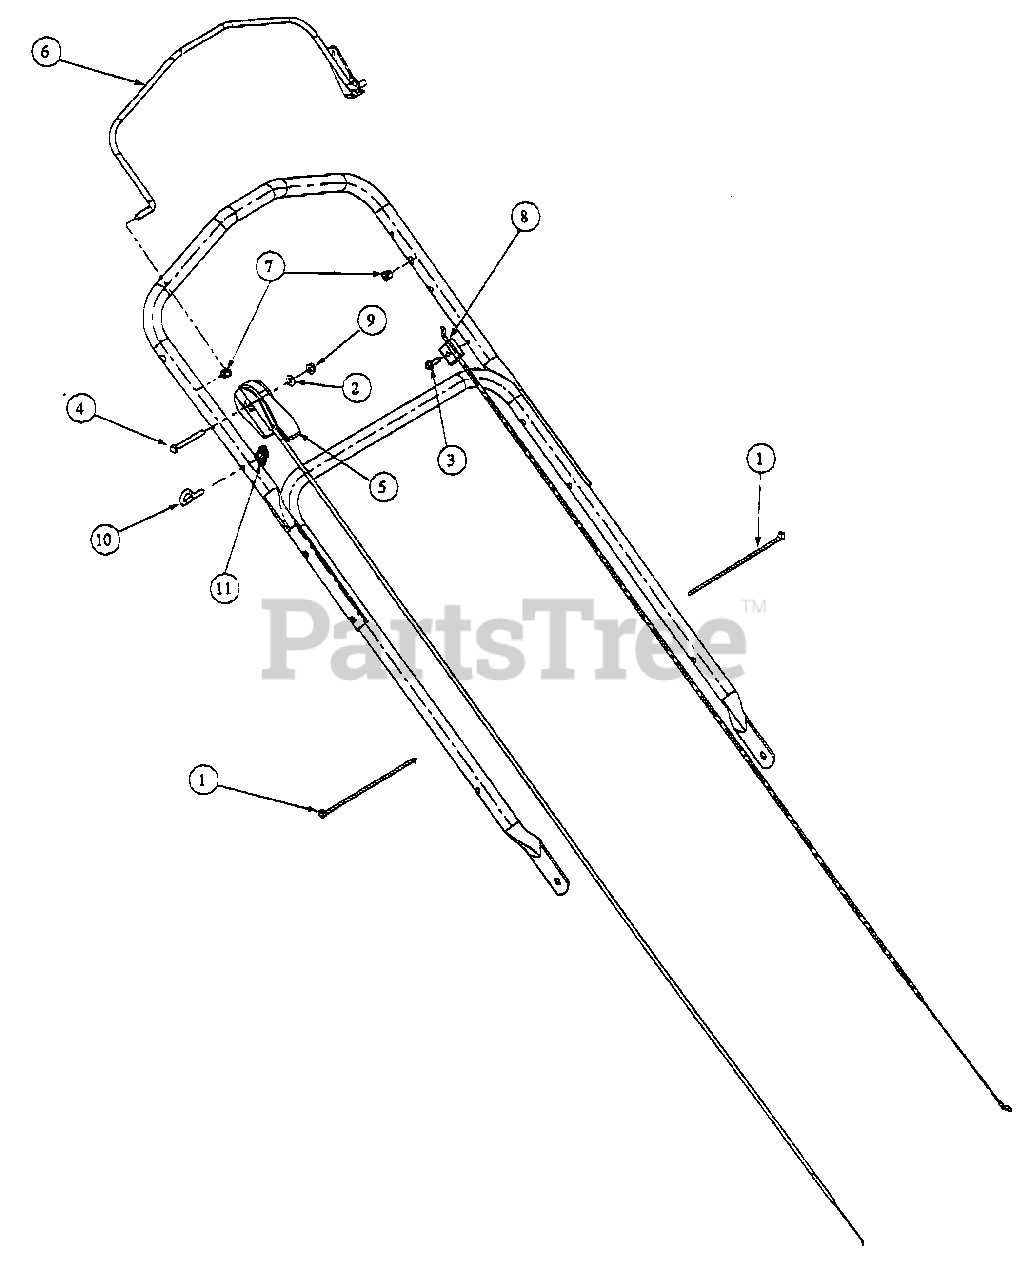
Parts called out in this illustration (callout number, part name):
1	Cable Tie, 3/16 X .05 X 7.4
2	Flatwasher 1/4 X .630 X .0515
3	Screw, TT, 1/4-20, 0.750, Hex Index Washer
4	HHCS, 1/4-20, 2.25, GR5, Standard
5	Control Throttle, W/Cable, KAW
6	Control Lever, W/O BBC
7	Bushing, .3125 Diameter. Snap
8	Control Cable, 45.75" Long, KAW
9	Nut, 1/4-20, Hex Flange, Lock, Group F
10	Eye Bolt, 1/4-20, Bent Rope GDE
11	Handle Knob, ERS 1/4-20
